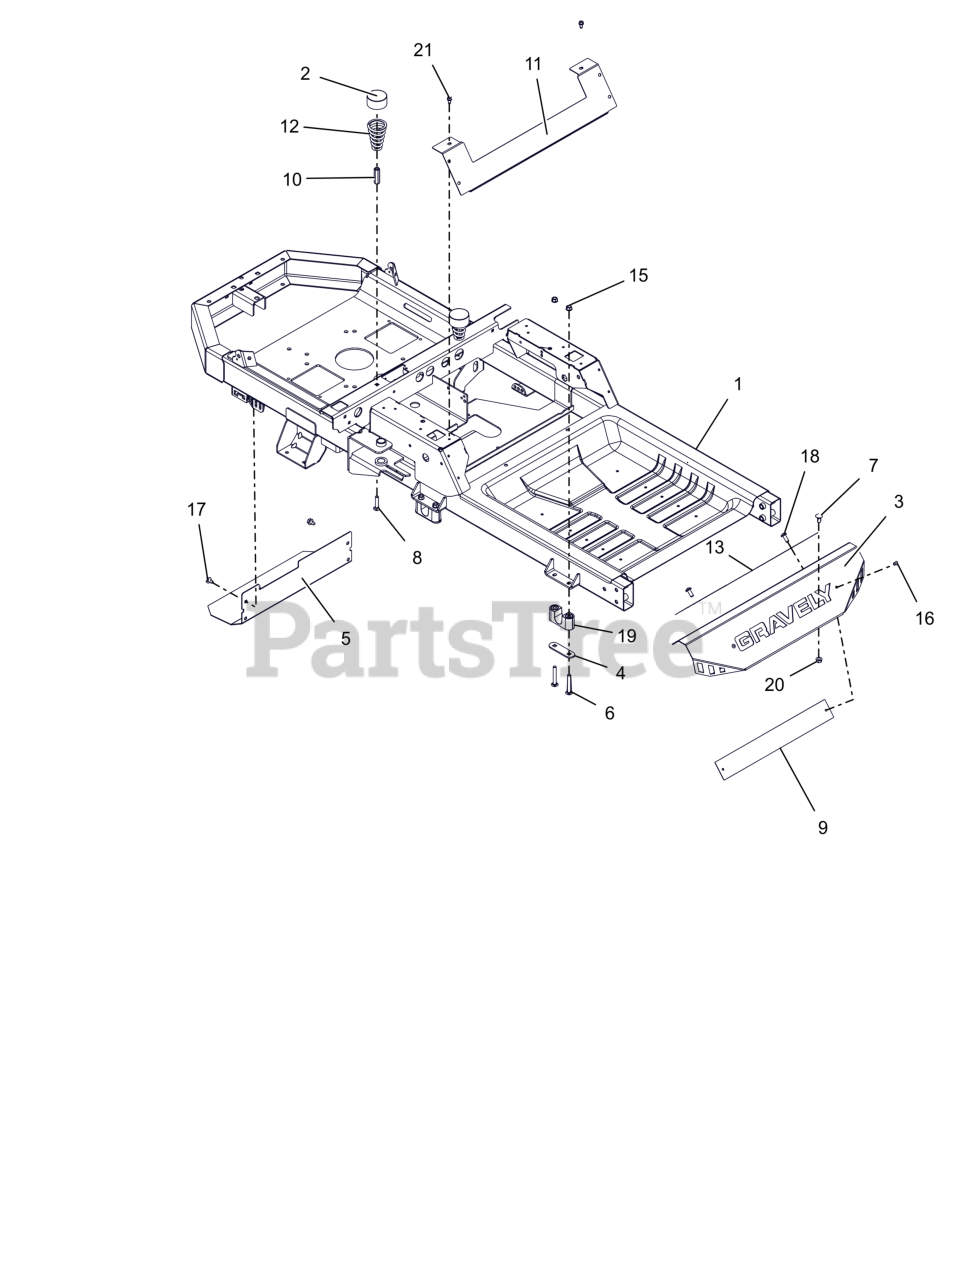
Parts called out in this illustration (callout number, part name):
1	WLDMT, FRAME IKON XD/ZTX & XL (RED)
3	KIT, FOOTPLATE W/DECAL-ZTX
4	PLATE, BEARING SUPPORT
5	HEAT, SHIELD
6	BLT, RHSSN.31-18X2.25 G5 ZCC
7	BLT,RHSN .31-18X.75 G5 ZCC
8	BLT,RHSN .31-18X1.50 G5 ZCC
9	PLATE, BACK FOOT-REST XL
10	NUT, COUPLING .31-18X1.75 ZCC
11	PLATE, SEAT KICK
12	SPRING, SEAT
13	GRIP, FOOT PLATE
15	NUT,LK-CTR-FLG .31-18 GF ZCC
16	RIVET, #66 STEEL POP PD BLACK
17	SCR,TAP .312-18X.50 HWH TR ZCC
18	SCR-RDHDSKTAP .31-18X.75
19	BSHG, DECK LIFT PIVOT
20	NUT-LK-TOP-FLG .312-18 GF ZCC
21	SCR-TAP .25-20X.50 HWH ZCC
